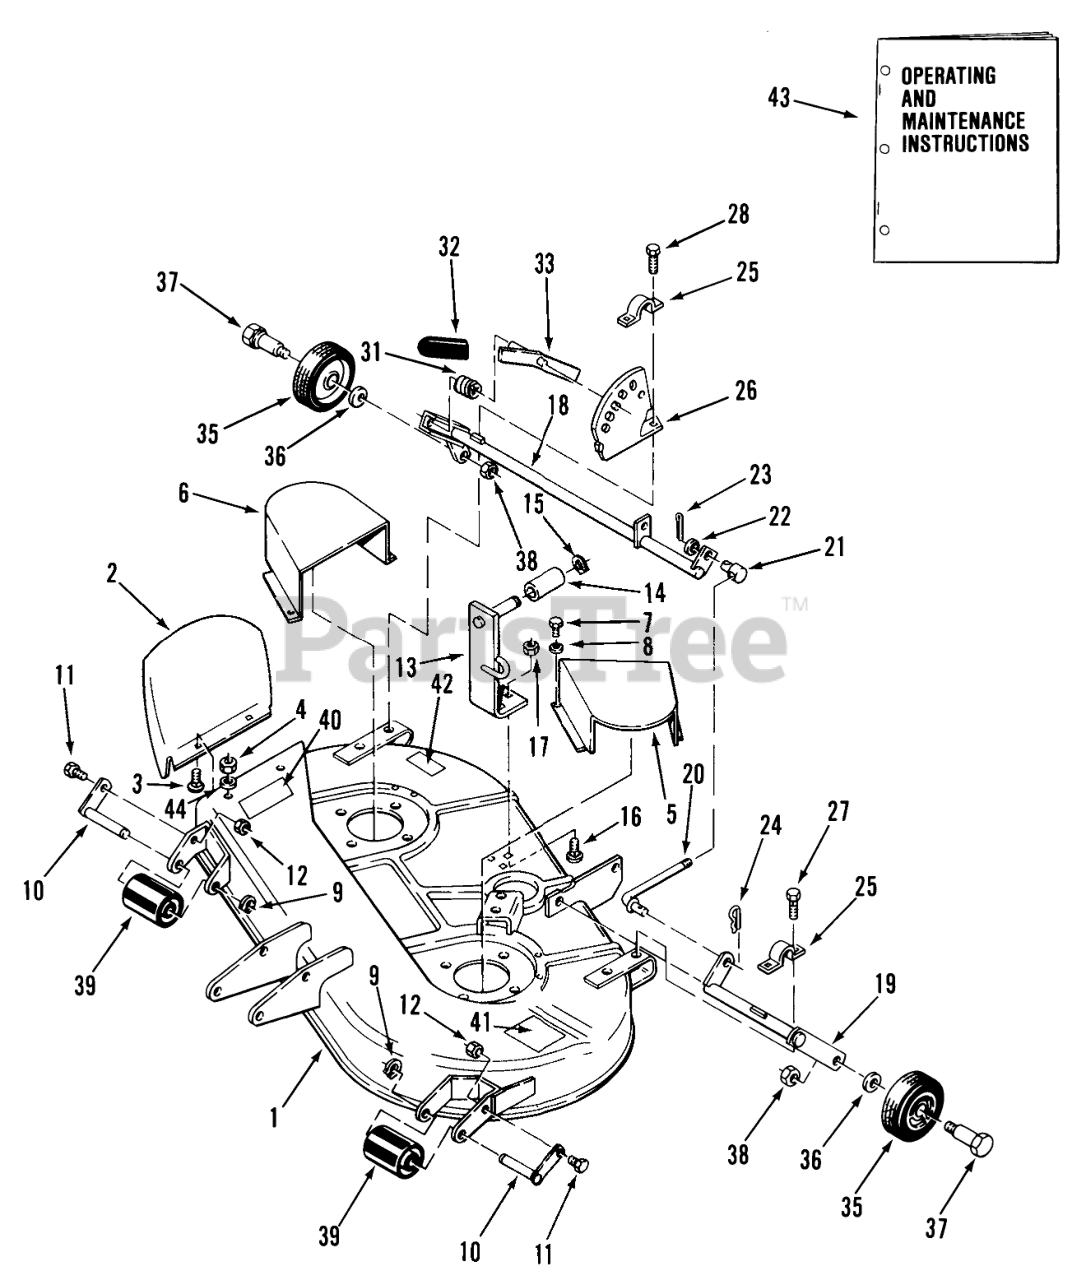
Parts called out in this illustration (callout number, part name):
1	Mower Deck
2	Chute Extension
3	CARRIAGE BOLT -4
4	Nut
5	COVER R
6	COVER R
7	Bolt
8	WASHER
9	Retaining Ring
10	Roller Shaft
11	H H C S
12	Nut
13	BRACKET ASSY R
14	SPACER
15	Snap Ring
16	BOLT HEX SPECIAL
17	Nut
18	Gage Wheel Support RH
19	WA GAG WHL R
20	Rod
21	TRUNNION
22	Washer
23	Pop Rivet
24	Hairpin
25	CLAMP
26	Quadrant
27	Bolt
28	Bolt
31	SPRING-COMPRESSION
33	Lever
35	Wheel 6 x 1.75
36	WASHER
37	BOLT-SHOULDER
38	Nut
39	Roller
40	DECAL
41	Caution Decal
42	DECAL-BELT&HEIGHT
43	Operating and Maintenance Instructions
44	WASHER 5/16 SAE
